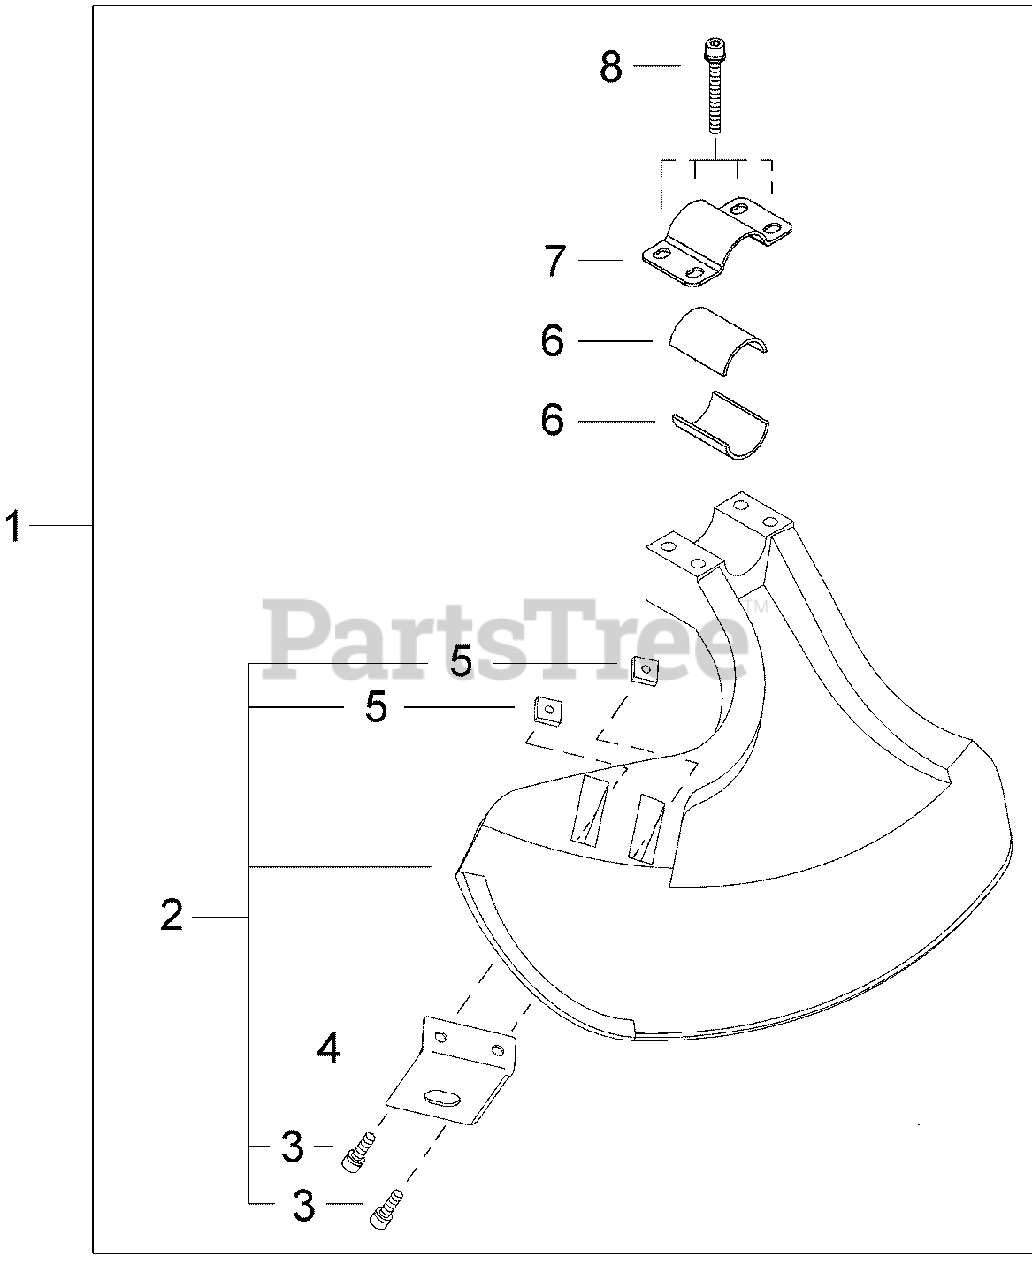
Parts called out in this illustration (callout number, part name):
1	DEBRIS SHIELD KIT
2	DEBRIS SHIELD ASSY
3	BOLT M5×16
4	CUTTER
5	NUT M5
6	SPACER 26
7	CLAMP, UPPER
8	BOLT M5×45
